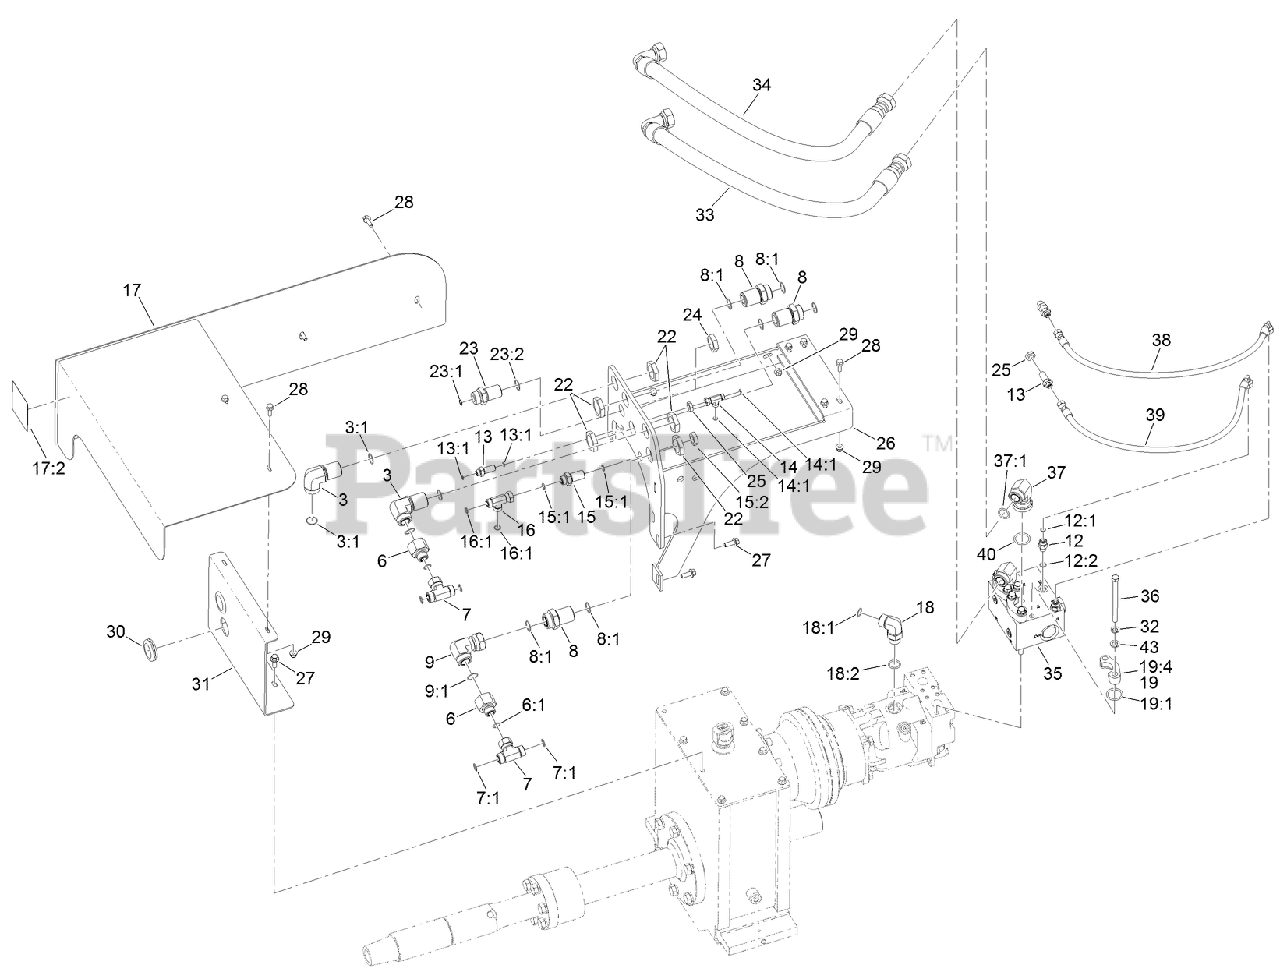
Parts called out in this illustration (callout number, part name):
3	FITTING-ELBOW, 90
3:1	O-RING
6	FITTING-REDUCER
6:1	O-RING
7	FITTING-HYD, TEE
7:1	O-RING
8	ADAPTER-HYD
8:1	O-RING
9	FITTING-SWIVEL, 90 DEG
9:1	O-RING
12	FITTING-STRAIGHT
12:1	O-RING
12:2	O-RING
13	UNION-BULKHEAD
13:1	O-RING
14	FITTING-HYD
15	FITTING-BULKHEAD
15:1	O-RING
15:2	NUT-BULKHEAD
16	FITTING-HYD, TEE
16:1	O-RING
17	CARRIAGE GUARD ASM
17:2	DECAL-WARNING
18	FITTING-ELBOW-90
18:1	O-RING
18:2	O-RING
19	HYD FLANGE KIT
19:1	O-RING
22	NUT-BULKHEAD
23	FITTING-STRAIGHT
24	NUT-BULKHEAD
25	NUT-LOCK
26	MOUNT-HOSE CARRIER, ROTARY
27	SCREW-HHF
28	SCREW-HHF
29	NUT-LOCK, HHF
30	GROMMET
31	PLATE-SUPPORT, GUARD
32	SCREW-HH
33	HYD HOSE ASM
34	HYD HOSE ASM
35	SPIKE CLIPPER MANIFOLD ASM
36	SCREW-HH
37	FITTING-ELBOW, 90 DEGREE
37:1	O-RING
38	HYD HOSE
39	HYD HOSE ASM
40	O-RING
43	SCREW-HH
